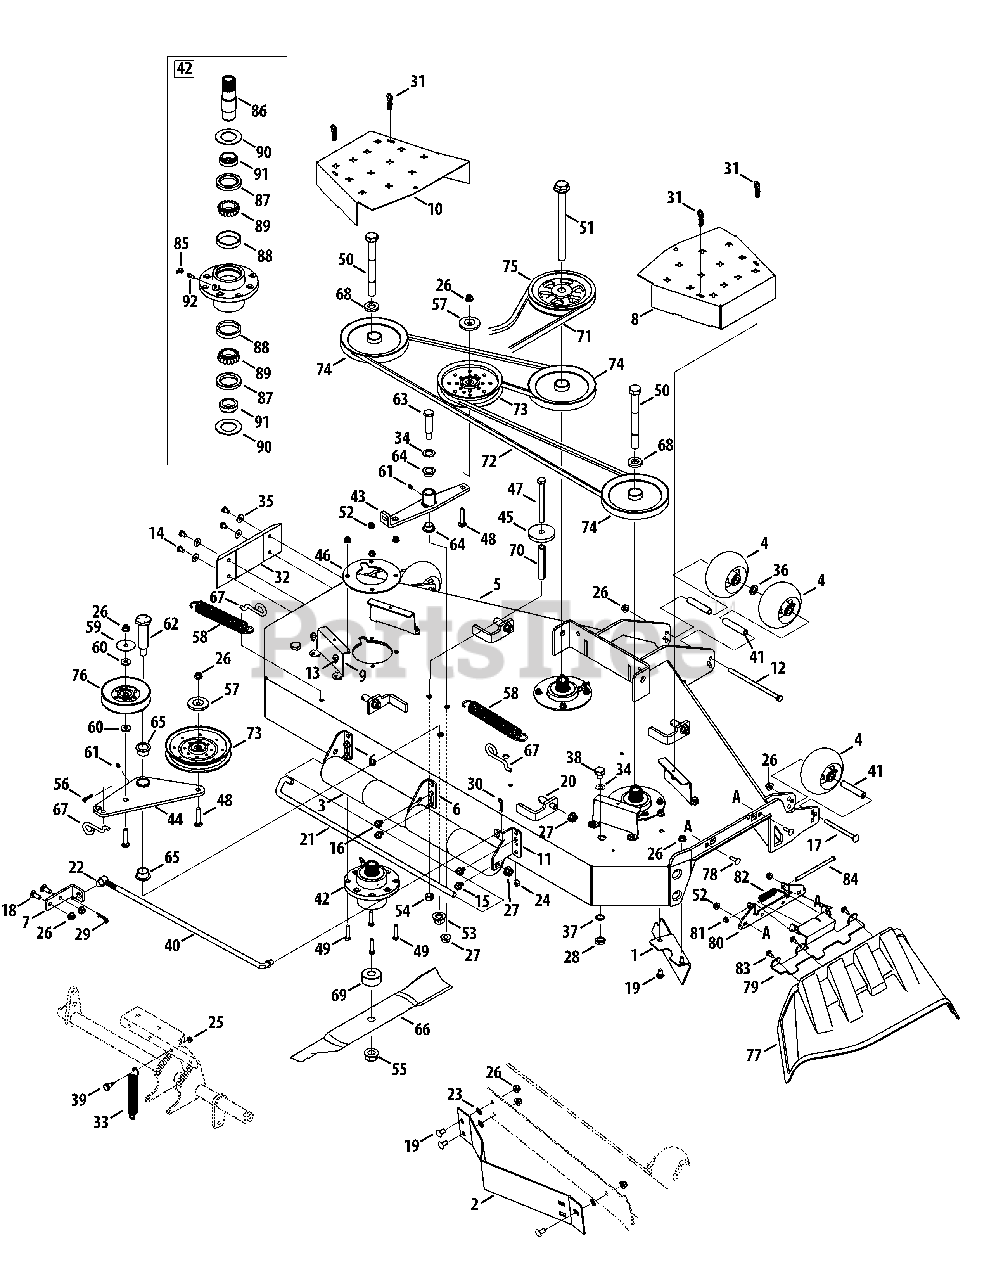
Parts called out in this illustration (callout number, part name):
2	Baffle, 60" Adjustment
3	Anti-Scalp Roller Assembly
4	Complete Wheel, 5.00 Dia.
6	Rear Roller Mount Bracket
7	Deck Stabilizer Mount Bracket
8	Deck Belt Cover, RH
9	Beck Belt Cover Bracket
10	Deck Belt Cover, LH
11	Rear Roller Bracket, RH
12	Hex Cap Screw, 3/8-16 x 7.25
13	Screw, 5/16-18 x .500
14	Screw, 5/16-18 x .500
15	Screw, 3/8-16 x .750
16	Screw, 3/8-16 x .500
17	Carriage Screw, 3/8-16 x 4.50
18	Carriage Bolt, 3/8-16 x 1.00
19	Carriage Bolt, 3/8-16 x .750
20	Pin, 1/2-13 x .625 x 1.2
21	J-Hook w/ Threaded Roller
23	Push Nut, 3/8
24	Jam Lock Nut, 3/8-16
25	Nut, 1/4-20, Flangelock
26	Nut, 3/8-16, Flangelock
27	Nut, 1/2-13, Flangelock
28	Hex Nut, M16-1.5
29	Click Pin, .092 x 1.64
30	Internal Cotter Pin
31	Folding Latch Panel
32	Skid Guard Plate
33	Extension Spring, .969 x 6.180
34	Washer, .793 x 1.24 x .06
35	Flat Washer, .343 x .880 x .062
36	Flat Washer, .632 x 1.00 x .160
37	Lock Washer, 17 x 23.8 x 1.95
38	Plug, Screw, M16-1.5
39	Shoulder Bolt, .437 x .50, 1/4-20
40	Deck Support Rod, 1/2" Dia.
41	Wheel Spacer
42	Spindle Assembly
43	Deck Idler Arm
44	Idler Assembly
45	Spacer, .5375 x 2.75 x .375
46	Spindle Support Plate
47	Hex Cap Screw, 1/2-13 x 5.00
48	Screw, 3/8-16 x 2.00
49	Bolt, 5/16-18 x 1.25
50	Hex Cap Screw, 3/4-16 x 7.00
51	Hex Cap Screw, 3/4-16 x 9.00
52	Nut, 5/16-18, Flangelock
53	Nut, 5/8-18, Flangelock
54	Nut, 1/2-13, Hexlock
55	Nut, 3/4-16, Flangelock
56	Bow Tie Cotter Pin
57	Pulley Cap
58	Extension Spring, 1.248 x 8.5
59	Washer, .406 x 1.92 x .060
60	Washer, .406 x 1.00 x .105
61	Grease Fitting
62	Shoulder Bolt, 1.0 x 3.15, 5/8-18
63	Shoulder Bolt, .750 x 2.23, 1/2-13
64	Flange Bearing, .75 x .52
65	Flange Bearing, 1.00 x .75
66	Hi-Lift Blade, 21.0
67	Spring Rod Hook
68	Spacer, .812 x .218
69	Spacer, .760 x 2.00 x .925
70	Spacer, .405 x .75 x 3.875
73	Idler Pulley
74	Spindle Pulley
75	Drive Pulley
76	Idler Pulley
77	Discharge Chute Assembly
78	Carriage Bolt, 5/16-18 x 1.00
79	Chute Bracket
81	Push Cap
82	Torsion Spring
83	Shoulder Screw, 1/4-20
84	Chute Rod
85	Grease Fitting, 45 degree, 1/4-28
86	Spindle Shaft
87	Seal, Oil
88	Cup Bearing
89	Cone Bearing
90	Washer, 1.50 x 2.52 x .075
91	Ring, Seal
92	Straight Adapter Fitting
